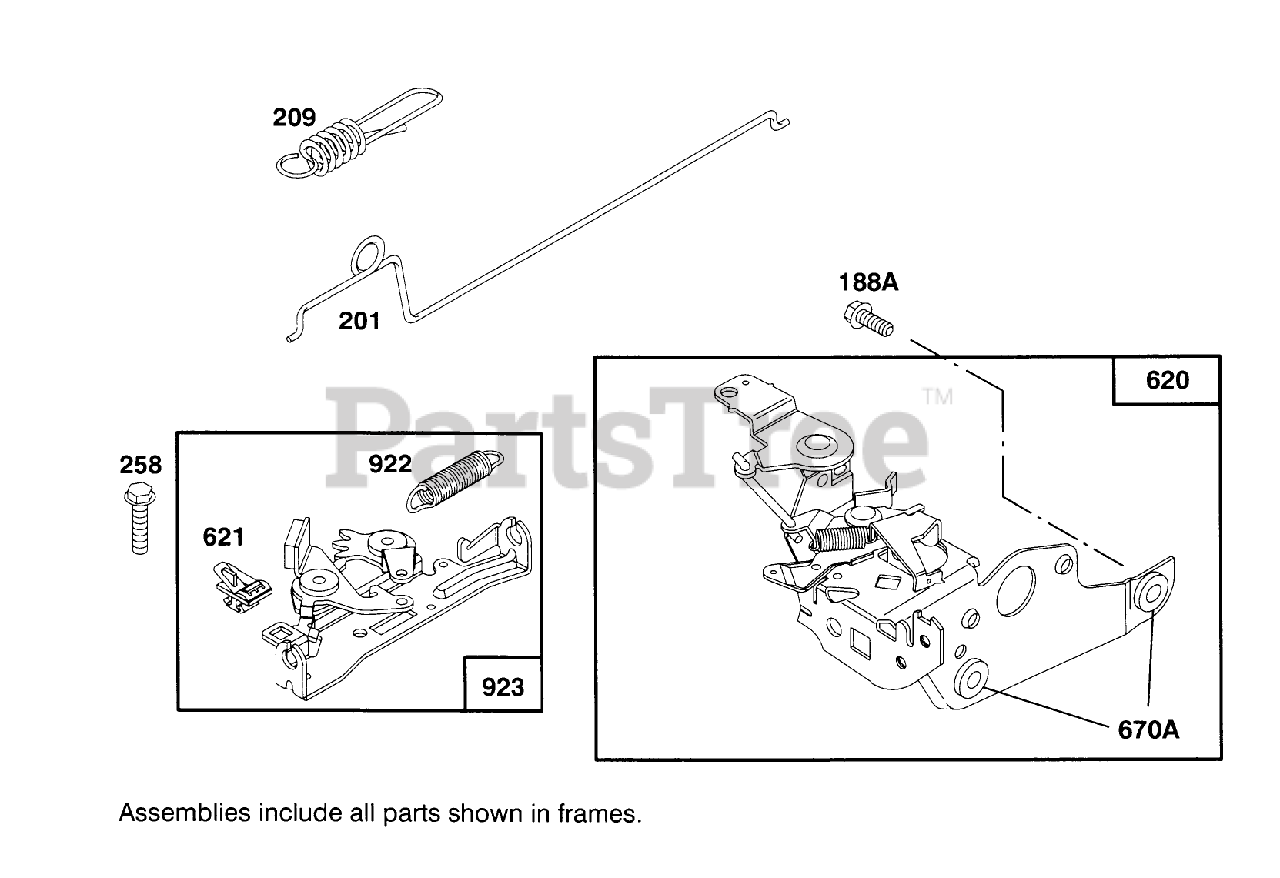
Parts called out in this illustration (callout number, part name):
188A	Screw-Hex.
201	Link-Govemor
209	Spring-Governor
258	Screw-Sem
620	Bracket-Carburetor
621	Switch
670A	Spacer
922	Brake Spring
923	Brake
